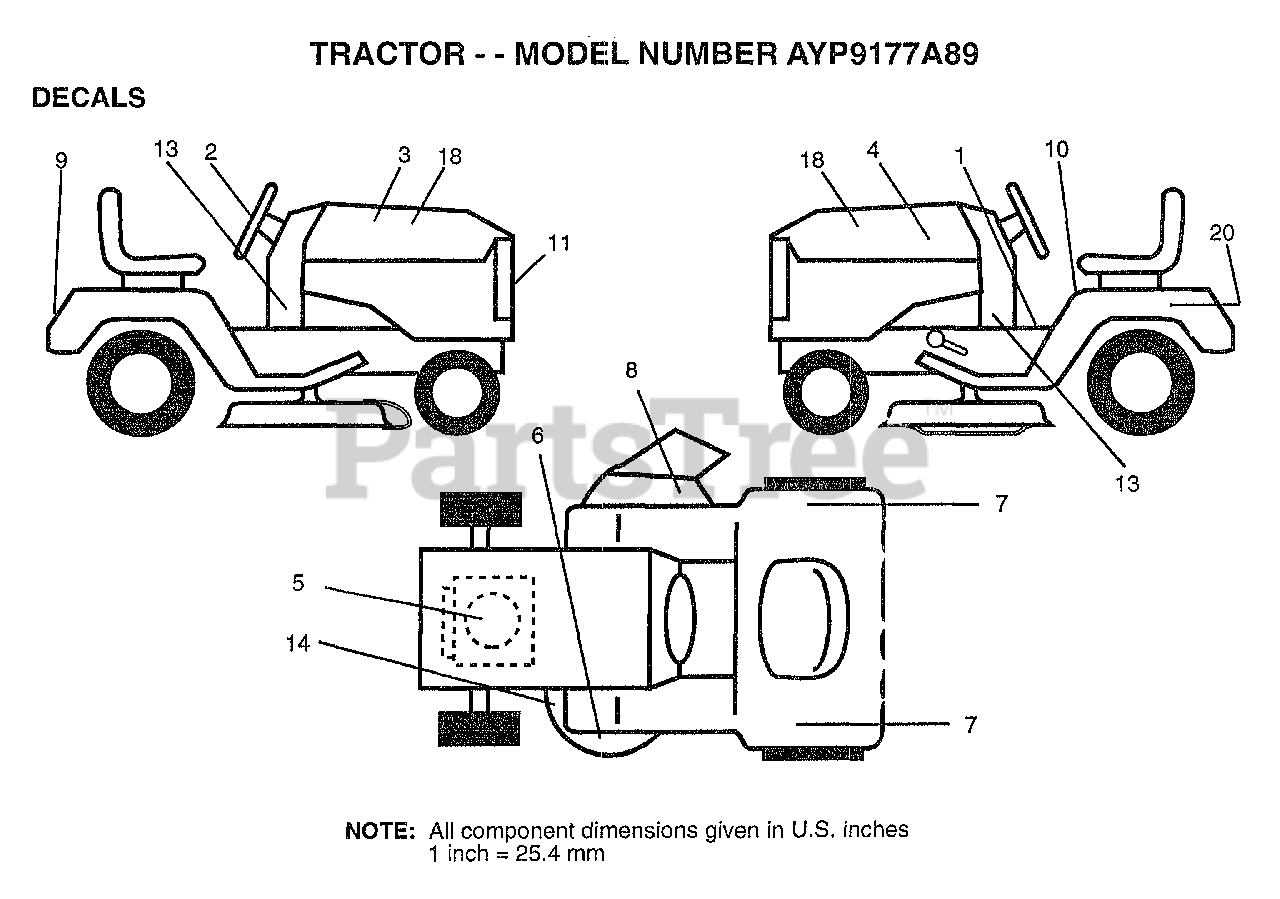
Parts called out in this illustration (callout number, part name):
1	"DEAL-OPER,INST."
2	DECAL STEER WHL
3	DECAL HOOD RH
4	DECAL HOOD LH
5	DECAL, HP ENGINE
6	DECAL DECK MULCH
7	DECAL.FENDER.AUTO
8	DECAL DECK WIZ +
10	"DECAL DANGER,FEND"
11	DECAL.LENS.WIZARD
13	DECAL.SIDE PANEL
14	"DECAL-SCHEM,BELT"
18	NAMEPLATE.HD.WIZA
20	DECAL.BATRY.3-3908
